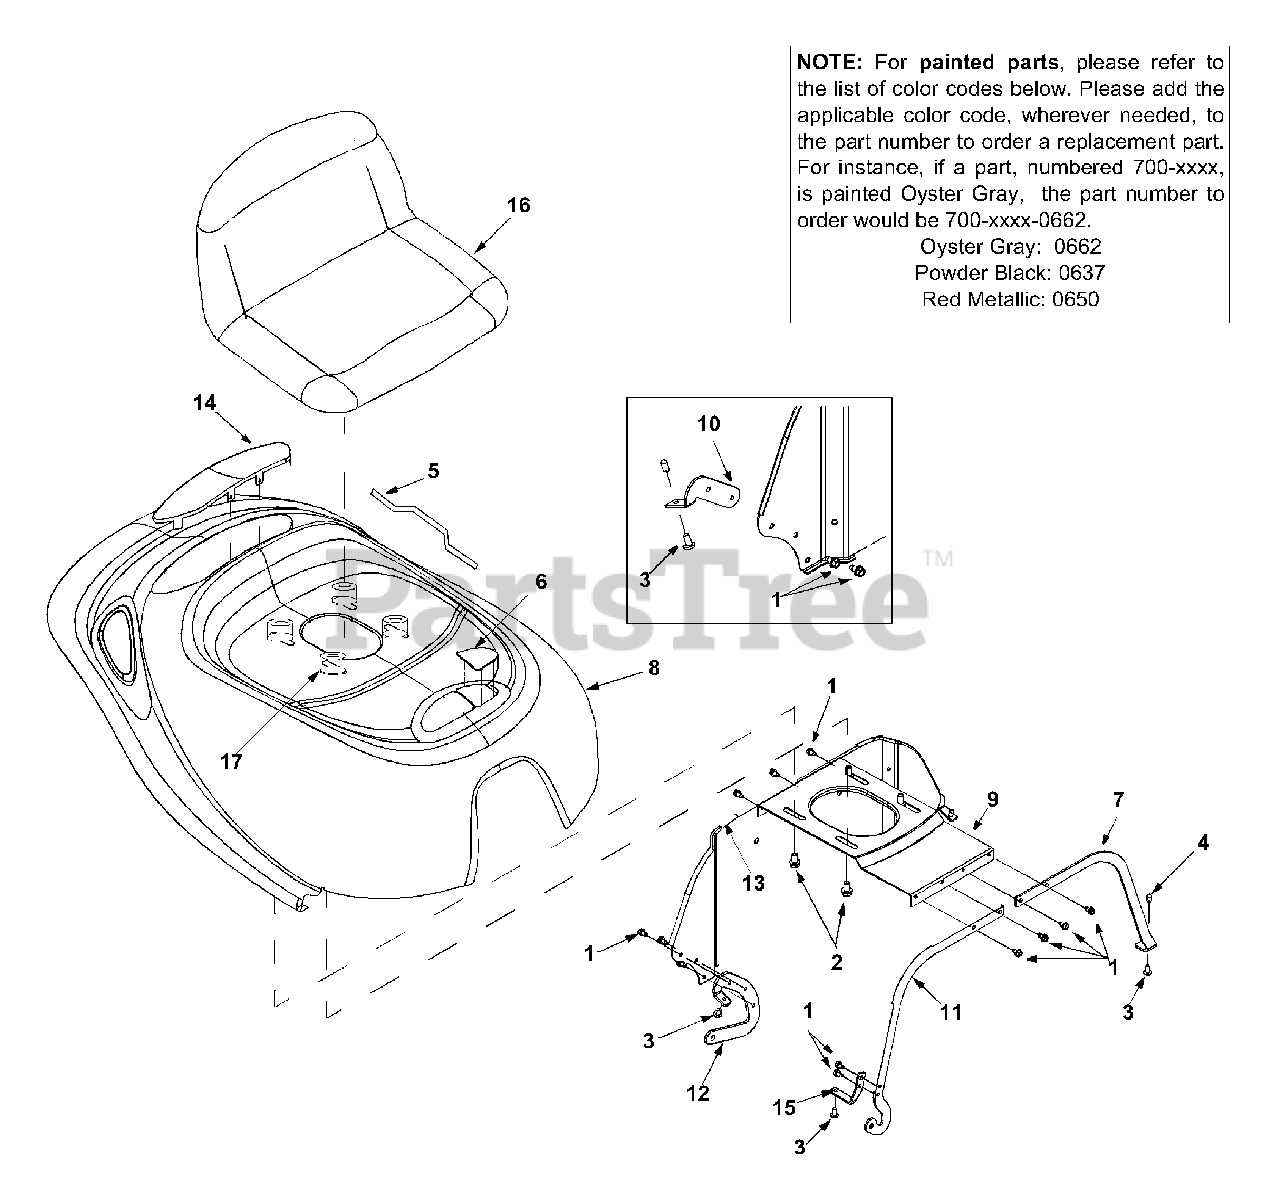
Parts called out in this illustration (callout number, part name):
1	TT Screw 1/4-20 x 0.5
2	TT Screw 3/8-16 x 1.25
3	Torx AB Screw 1/4-14 x 0.625
4	Rod End Grip
6	Grass Bag Lens
17	Spacer
